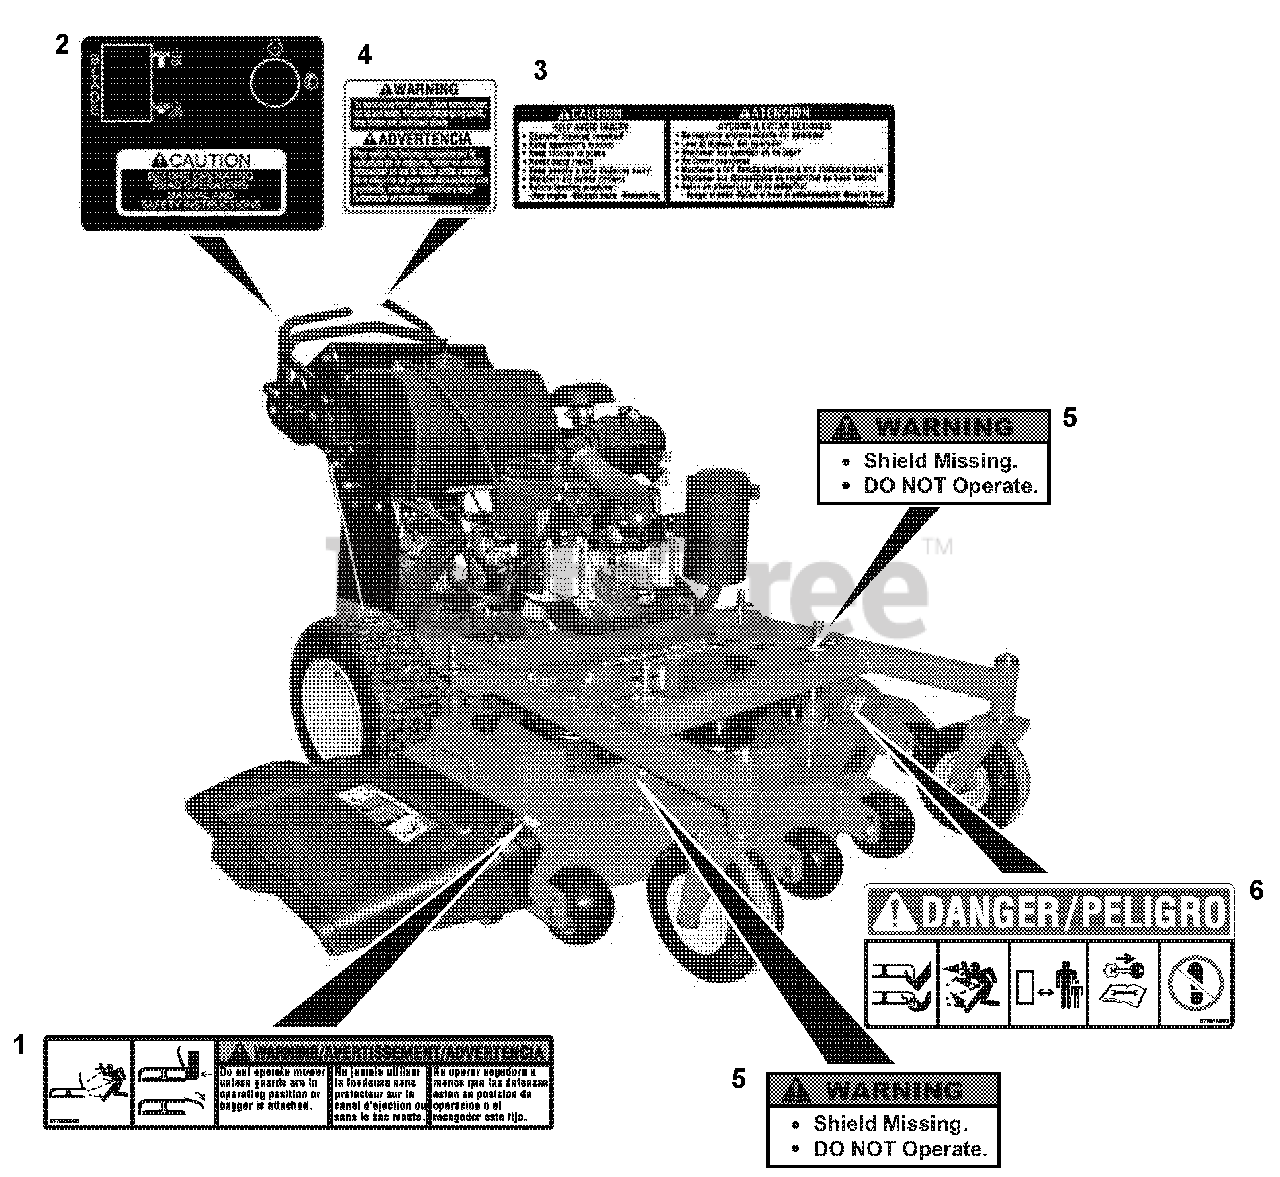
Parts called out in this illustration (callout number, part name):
1	Decal, Warning
2	Decal, PTO and Key Switch
3	Decal, General Caution
4	Decal, Warning - Slope
5	Decal, Warning - Shield
6	Decal, Mower Pan Danger
